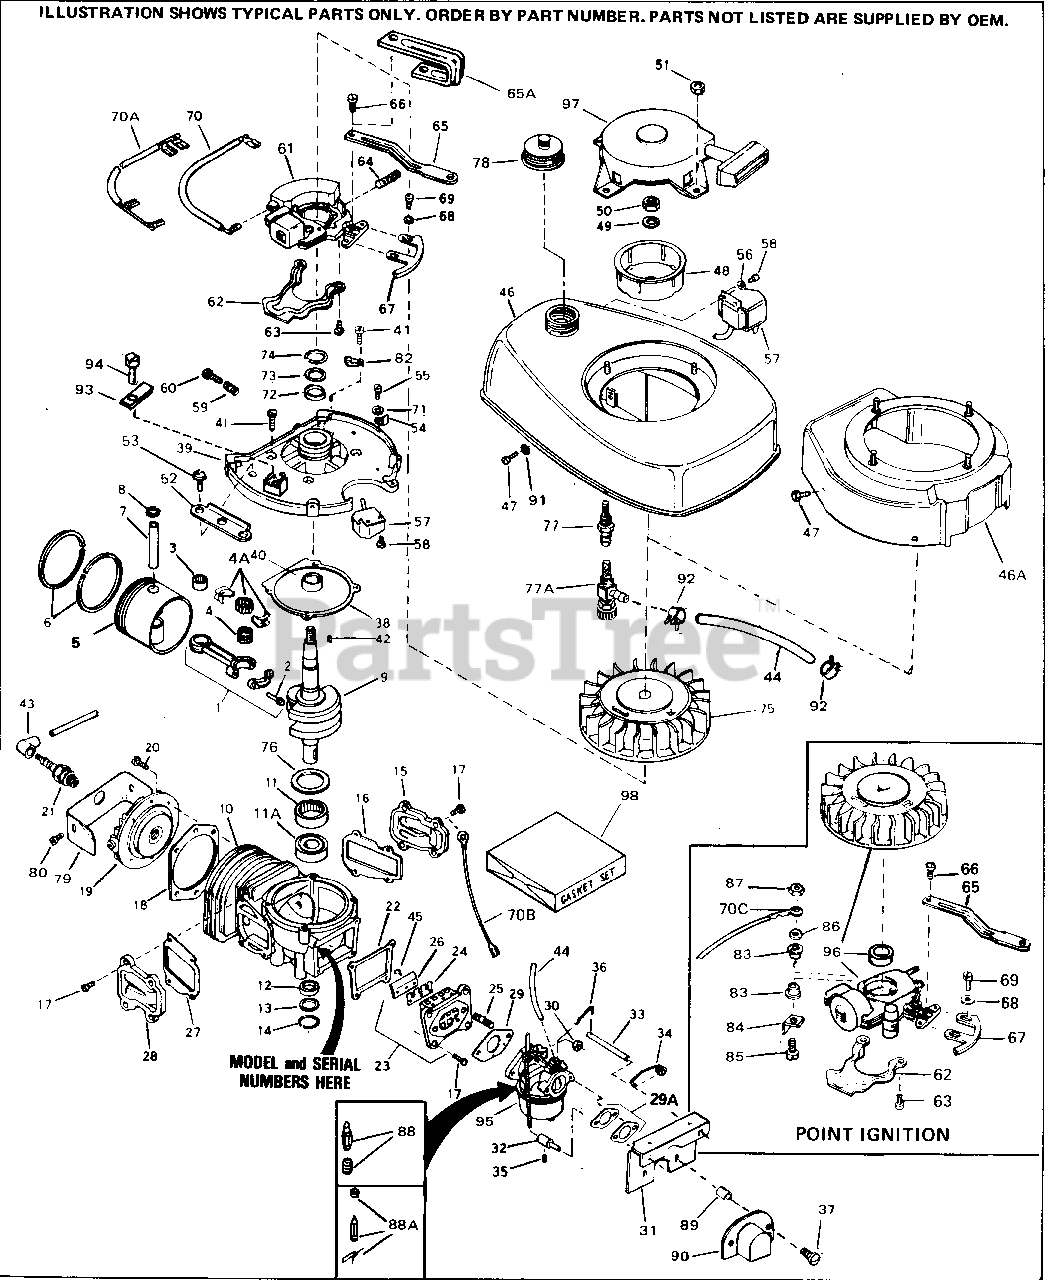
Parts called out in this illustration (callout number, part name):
1	"Rod Assy., Connecting
2	Screw, Connecting rod
3	Bearing, Cartridge
4A	Bearing & Liner Set, Needle (31 needl es)
5	Piston & Pin Assy.
6	Ring Set, Piston
7	Pin, Piston
8	Ring, Piston pin retaining
9	Crankshaft
10	Block Assy., Cylinder
11A	Bearing, Ball
12	Seal, Crankshaft
15	Plate, Cover
16	Gasket, Cover plate
17	Screw, Int. Torx hd., 10-24 x 1/2
18	Gasket, Cylinder head
19	Head, Cylinder
20	Screw, Torx pan hd., 1/4-20 x 3/4
21	Plug, Spark (RJ12YC or equivalent)
22	Gasket, Reed & Cover plate
23	Plate Assy., Reed & Cover
25	Stud, Carburetor
26	Stop, Reed
27	Gasket, Cover plate
28	Plate, Cover
29	Gasket, Carburetor
30	Nut, Flange whizlock, 1/4-28
38	Gasket, Housing base
39	Base Assy., Housing
40	Bearing, Needle
41	Screw, Hex washer hd. Durlok, 1/4-20 x 5/8
42	Key, Flywheel
43	Cover, Spark plug
44	Line, Fuel (8-1/4" long)
44	Line Fuel (16" long)
45	Screw, Pan washer hd., 4-40 x 3/16
46A	Housing, Blower
47	Screw,Hex washer hd., 1/4-20 x 3/4
48	Cup, Starter
49	Washer, Belleville
50	Nut, Hex Jam
51	Nut, Flange whiz lock, 1/4-28
55	Screw, Pan flex hd., 10-24 x 3/8
57	Transformer Assy.
58	Screw, Pan flex hd., 10-24 x 3/8
59	Spring, Compression
60	Screw, Rd. hd., 8-32 x 7/8
61	Magneto, Solid state
62	Bracket, Neutral clutch
63	Screw, Pan hd. taptite, 6-32 x 3/8
64	Screw Assy., Friction
65A	Lever, Control
66	Screw, Pan flex hd., 10-24 x 3/8
68	Washer, Flat 5/16
69	Screw, Torx pan hd., 6-32 x 3/8
70	Wire, Primary
71	Washer, No. 10 Flat
72	Seal, Crankshaft
73	Retainer, Crankshaft seal
74	Spring, Crankshaft seal retainer
75	Flywheel
79	Extension, Blower housing
80	Screw, Hex washer hd., 1/4-20 x 3/4
88A	Inlet Needle, Seat & Clip Assy.
91	Washer, Flat 1/4
93	Bracket
94	Screw, Int. Torx hd., 10-24 x 1/2
95	Carburetor
97	Starter, Rewind
98	Gasket Set
